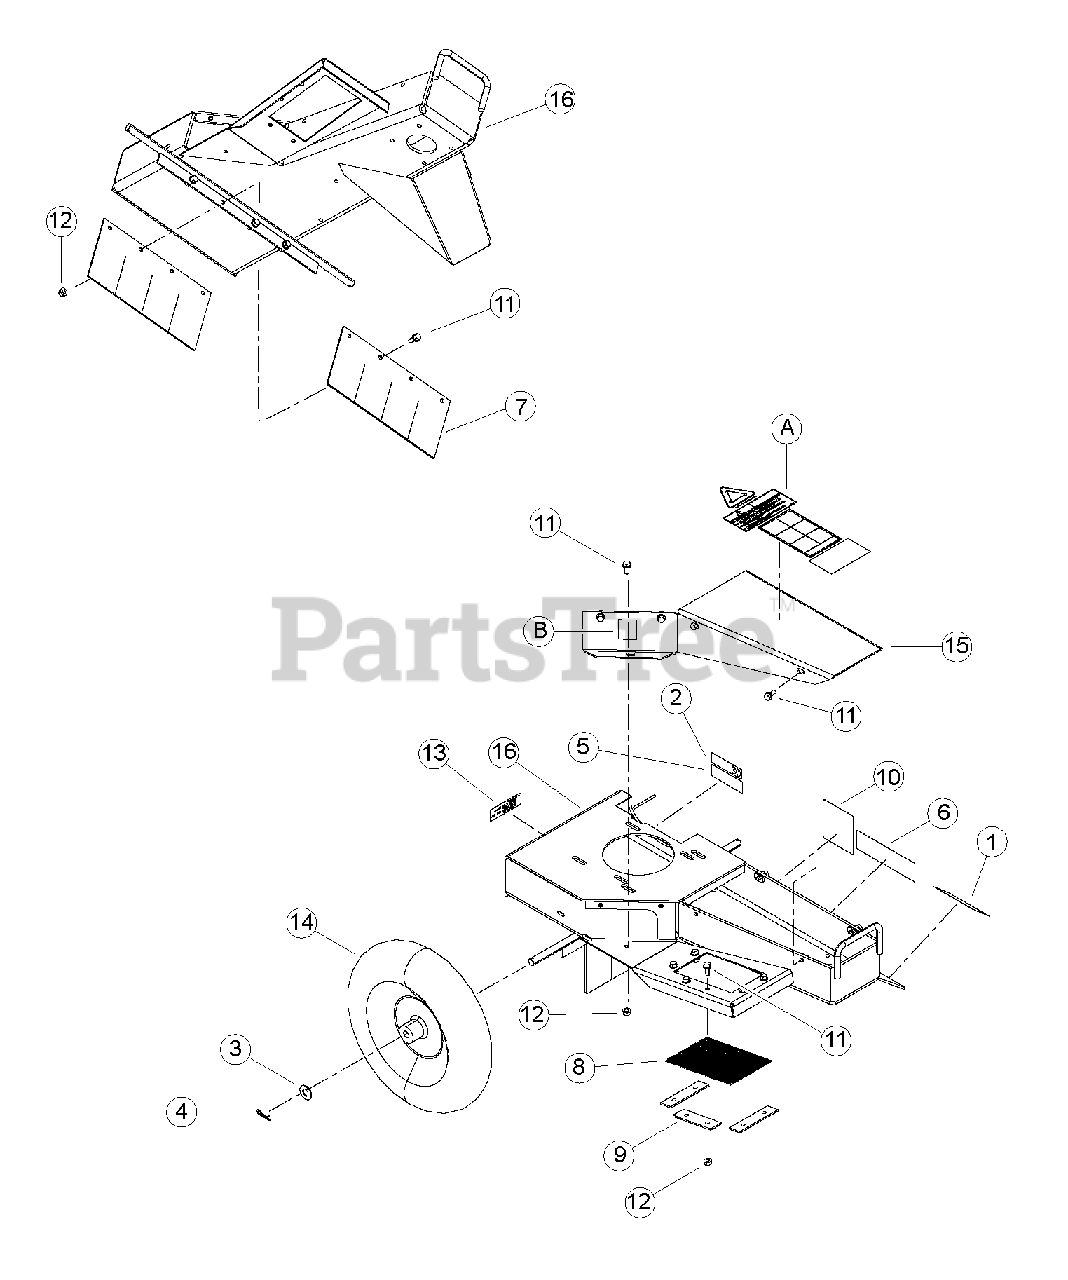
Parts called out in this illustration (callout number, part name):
1	DECAL, GRINDER DANGER
2	DECAL, STUMPGRINDER INFO
3	WASHER, 5/8 SAE FLAT ZP
4	HAIRPIN CLIP ZP #203
5	DECAL, SERIAL NUMBER
6	DECAL, ECHO BEARCAT 6.82 X 1.90
7	MUD FLAP, STUMP GRINDER
8	DEBRIS SCREEN, STUMP GRINDER
9	SCREEN CLAMP, STUMP GRINDER
10	DECAL, 87 DB
11	BOLT, 5/16 X 3/4 FLANGE NC
12	NUT, 5/16-18 NYLOCK-FLANGE
13	DECAL, ATLANTIC BRIDGE LTD INFO
14	ASSEMBLY, TIRE AND WHEEL
15	ASSEMBLY, TOP STUMPGRINDER COVER
16	WELDMENT, STUMPGRINDER FRAME
A	DECALS (12254, 12172, 14942-00, 31511-00)
B	DECAL, QR CODE
